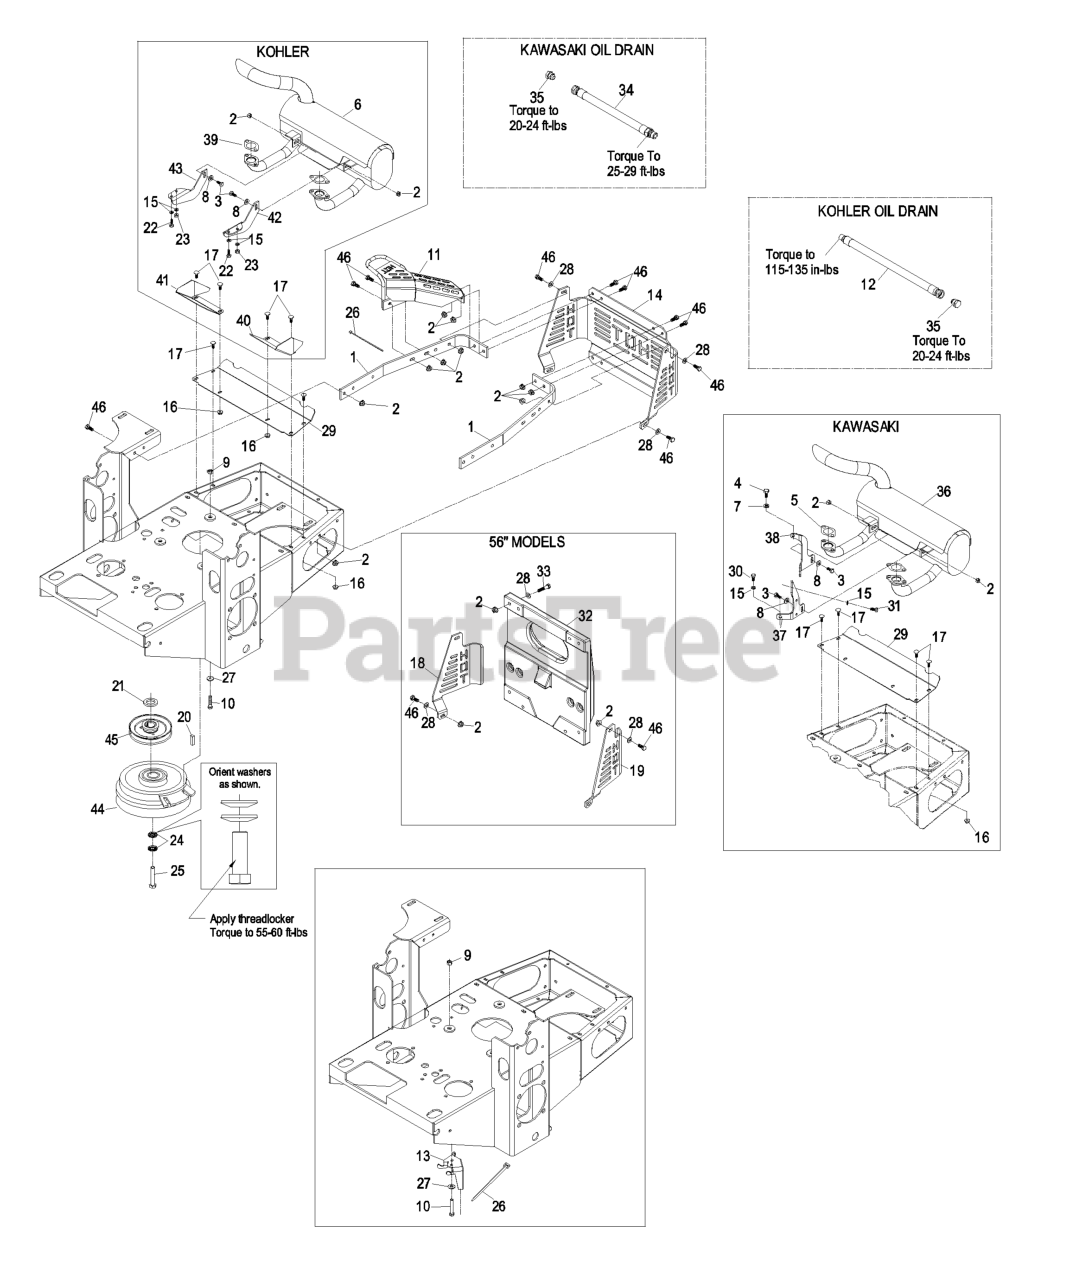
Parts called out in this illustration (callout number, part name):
1	STRAP-GUARD, RH
3	SCREW-HH
4	SCREW-HH
5	GASKET-EXHAUST
6	KIT,MUFFLER (18-23 KOH)
7	WASHER-LOCK
8	WASHER-FLAT
9	NUT-LOCK, NI
10	SCREW-HH
11	GUARD-TAILPIPE
13	ANCHOR,CLUTCH HD
14	GUARD-REAR
15	WASHER-LOCK
16	NUT-HF
17	SCREW-CARR
18	GUARD-MUFFLER, RH
19	GUARD-MUFFLER, LH
21	SPACER,1.63 X1.14 X .18
22	SCREW-HH
23	NUT-HEX
24	WASHER-SPRING
25	SCREW-HH
26	TIE-PLASTIC
27	WASHER-SPRING
28	WASHER-PLAIN
29	DEFLECTOR-SHORT
30	SCREW-HH
31	SCREW-HH
32	WEIGHT-NOTCHED, 60 LB
33	SCREW-HH
36	MUFFLER KIT
37	BRACKET-MUFFLER, LH
38	BRACKET-MUFFLER, RH
40	DEFLECTOR-AIR, LH,KC
41	DEFLECTOR-AIR, RH,KC
42	BRACKET-MUFFLER, LH
43	BRACKET-MUFFLER, RH
44	CLUTCH KIT
45	PULLEY
46	SCREW-HH
